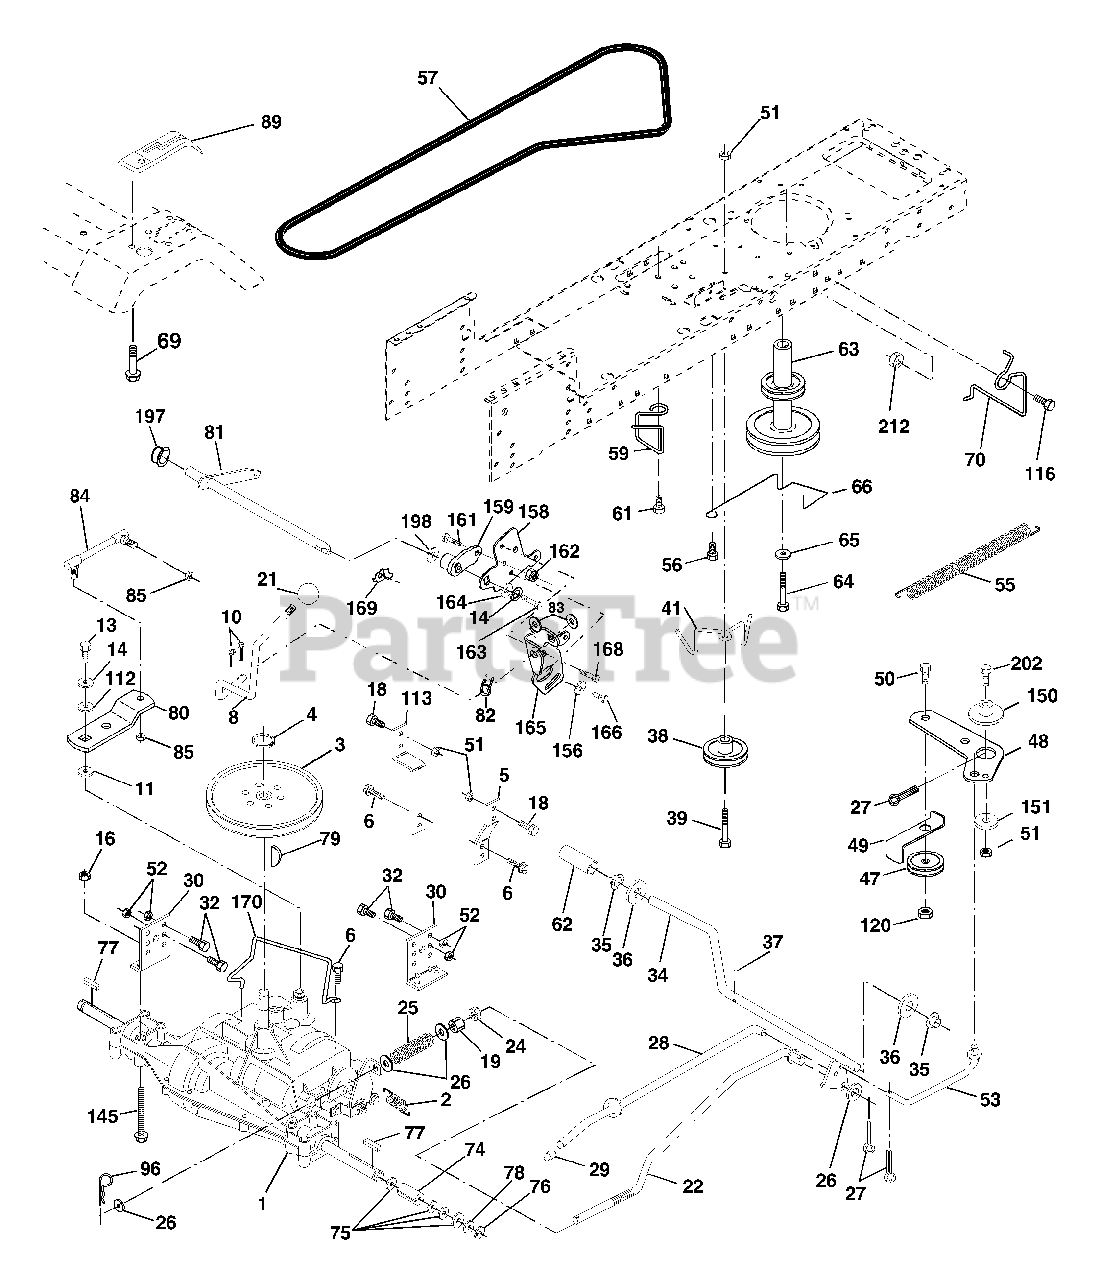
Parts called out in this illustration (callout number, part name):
2	Spring Return Brake T/a Zinc
3	Pulley Transaxle 18/20" tires
4	Ring Retainer # 5100-62
5	Strap Torque 30 Degrees
6	Screw 5/16-18 x 3/4
8	Rod Shifter Fender STLT
10	Pin Cotter 1/8 x 1 Cad
11	Washer Plate Shf 388 Sq Hole
13	Bolt 1/4-28unf Gr8 W/Patch
14	Washer Lock Hvy Helical 1/4
16	Nut Lock Hex w/Ins. 5/16-18 Unc
18	Bolt Fin Hex 3/8-16 Unc x 1 Gr 5
19	Nut Lock Hex w/Ins. 38/-16 Unc
21	Knob Deluxe
22	Rod Brake Blk Zinc 26 840
24	Nut Hex Jam 3/8-16 Unc
25	Spring Rod Brake 2 00 Zinc
26	Washer 13/32 x 13/16 x 16 Ga.
27	Pin Cotter 1/8 x 3/4 Cad
28	Rod Brake Parking Lt/Yt
29	Cap Brake Parking
30	Bracket Mtg Transaxle
32	Bolt Hex Hd 5/16-18 Unc x 3/4
34	Shaft Asm Pedal Foot
35	Bearing Nylon Blk 629 Id
36	Washer 21/32 x 1 x 16 Ga
37	Pin Roll 3/16 x 1"
38	Pulley Composite Flat
39	Bolt Fin Hex 3/8-16unc x 3
41	Keeper Belt Idler
47	Pulley Idler
48	Bellcrank Clutch Grnd Drv STL
49	Retainer Belt Style Spring
50	Bolt Hex Hd 3/8-16 Unc x 1-1/2
51	Nut Crownlock 3/8-16 UNC
52	Nut Crown Lock 5/16-18
53	Link Clutch 7 66
55	Spring Return Clutch 6 75
56	Screw 3/8-16 x 1-1/4
57	V-Belt Gd Drive
59	Keeper Belt Centerspan
61	Screw 3/8-16 x .875
62	Cover Pedal Blk Round
63	Pulley Eng
64	Bolt Hex 7/16-20 x 4 Gr 5
65	Washer Lock Hvy Hlcl Spr 7/16
66	Keeper Belt Engine
69	Screw Hex Wsh Hi-Lo 1/4-1/2 Unc
70	Guide Belt Mower Drive RH
74	Spacer Split
75	Washer 25/32 x 1 1/4 x 16 Ga
76	E-ring #5133-75
77	Key Square
78	Washer 25/32 x 1-5/8 x 16ga
79	Key Woodruff
80	Arm, Shift
81	Shaft Assembly
82	Spring, Torsion
83	Washer 17/32 x 3/4 x 16 Gauge
84	Link Transaxle
85	Nut, Nylock
89	Console, Shift, STLT
96	Retainer Spring
112	Washer 9/32 x 3/4 x 10 Ga
113	Strap Torque
116	Bolt Rd Hd Sqnk 3/8-16 x 1 Unc
120	Nut Lock Flg. 3/8-16 Unc
145	Bolt Hex Flghd 5/16-18 x Gr.5
150	Spacer Retainer
151	Washer 13/32 x 2 x 10 Ga.
156	Washer Srrted 5/16ID x 1 .125
158	Bracket Shift Mount
159	Hub Tapered Flange Shift Lt
161	Bolt Rdhd Sqnk 1/4-20 x 3/4 Gr.5
162	Nut Crownlock 1/4-20 UNC
163	Bolt Hex Fin 1/4-20 UNC x 1 Gr.5
164	Washer 5/8 x .281 x 10 Ga.
165	Bracket Pivot Lever
166	Screw 5/16-18 x 5/8
168	Bolt shoulder 5/16-18 x .561
169	Plate Fastening Lt
170	Keeper Belt T/A
197	Nyliner Snap-In 5/8" ID
198	Washer Nyl 7/8ID x .105"
202	Bolt Carr Sh 3/8-16 x 1-1/2 Gr.5
212	Nut Hex Flange Lock
